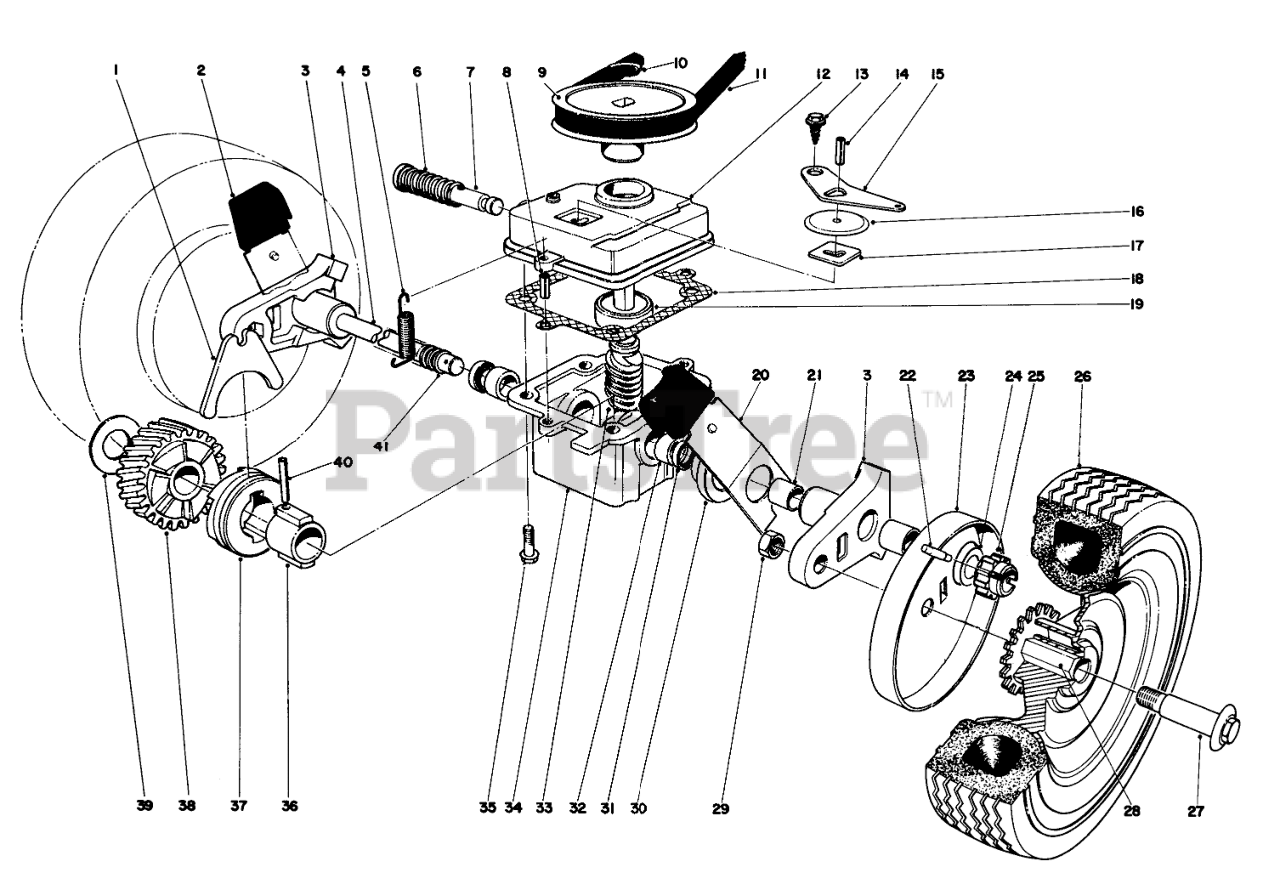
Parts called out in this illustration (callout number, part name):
1	SHIFTER FORK
2	KNOB-ARM
3	Pivot Arm (Incl. Ref. No. 21)
4	Drive Shaft
5	TENSION SPRING
6	SPRING
7	Shift Rod
8	3/16 X 1/2 ROLL PIN
9	PULLEY
10	PUSH-ON 93-3236
11	V BELT
12	GEAR CASE COVER
13	Screw
14	PIN-ROLL
15	SHIFTER ARM
16	TRANS DUST COVER
17	LATCH PLATE
18	GASKET
19	Bearing
20	SPRING ARM ASM SP
21	BUSHING
22	PIN-GROOVED
23	WHEEL COVER
24	WASHER-THRUST
25	Pinion
26	Bushing
28	WHEEL BUSHING
29	Nut
30	End Cap
31	Seal
32	Bushing
33	WORM SHAFT
34	Gear Case (Incl. Ref. No. 31-32)
35	Screw
36	SLEEVE
37	CLUTCH JAW
39	THRUST WASHER
40	COIL PIN
41	COVER-SHAFT, DRIVE
